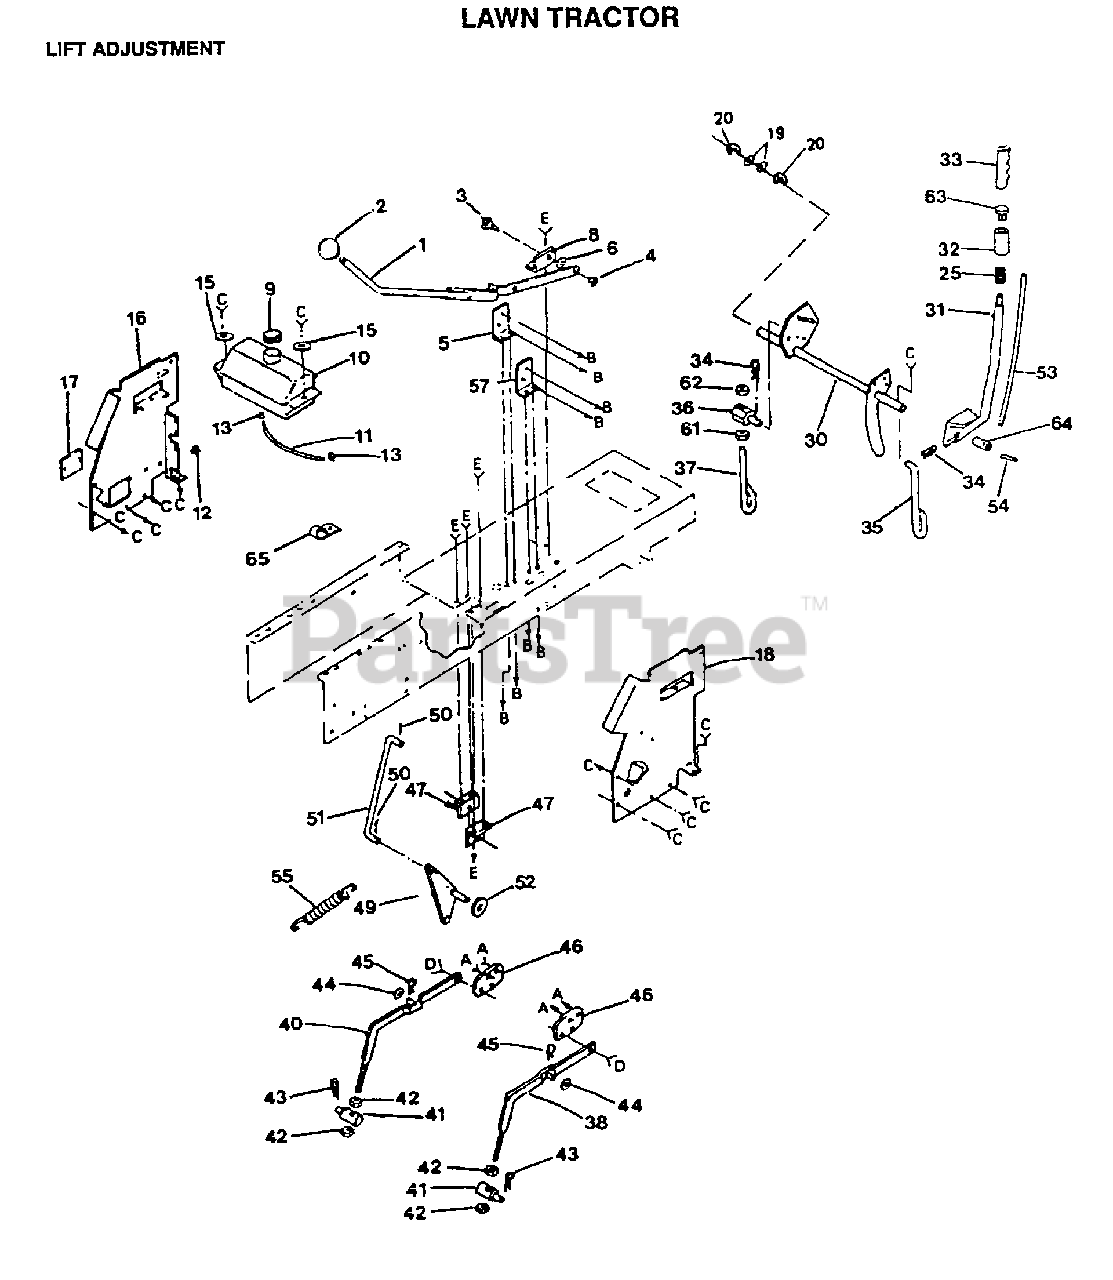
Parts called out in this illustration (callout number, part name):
3	"BOLT, SHOULDER LT"
5	"BRACKET,SWITCH LT"
8	"SUP,LVR,CLUTCH LT"
10	TANK.FUEL.LT.
11	FUEL LINE T
12	SNAP BUSHING T
13	HOSE CLAMP
15	WASHER GT
17	COVER ACCESS
18	"PANEL,DASH RH"
19	WASHER
20	E-RING
25	SPRING T
31	LEVER ASSY LT
33	GRIP
35	LIFT LINK LT
37	PIVOT PIN T
38	RH SUSP ARM ASM
40	LH SUSP ARM ASM
42	NUT
43	SPRING H
45	SPRING.RETAINER
46	"BRACKET, SUSPE T"
47	"BRKT,BELLCRAN T"
49	"T, BELLCRANK"
50	COTTER PIN
51	ROD CLUTCH T
52	WASHER
54	PIN-GROOVE LT
57	BRACKET LT
61	NUT
64	COUPLE LEVER T
65	INSUL CLIP T
